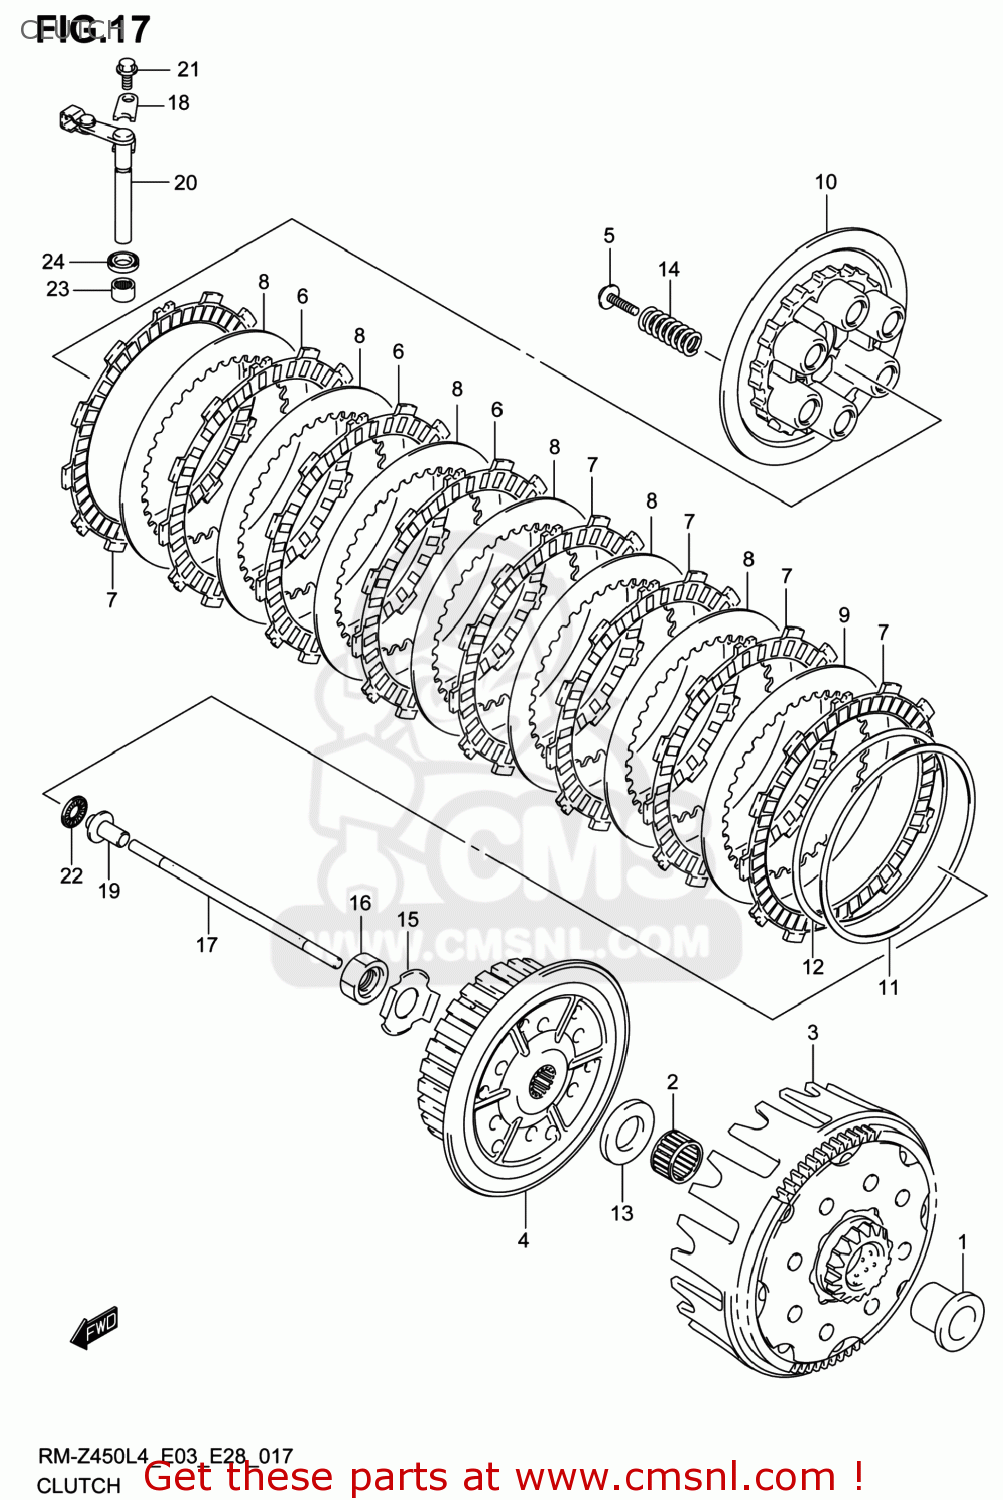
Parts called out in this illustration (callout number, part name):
1	SPACER,PRIMARY DRIVEN GEAR
2	BEARING(28X32X26)
3	GEAR ASSY,PRI DRIVEN
4	HUB,CLUTCH SLEEVE
5	BOLT,CLUTCH SPRING(6X25)
6	PLATE,CLUTCH DRIVEN NO.1 (NAS)
7	PLATE,CLUTCH DRIVE NO.2 (NAS)
8	PLATE,CLUTCH DRIVEN (NAS)
9	PLATE,CLUTCH DRIVEN (NAS)
10	DISC,CLUTCH PRESSURE
11	SEAT,WAVE WASHER
12	WASHER,CLUTCH PLATE WAVE
13	WASHER(22.5X39X3)
14	SPRING
15	WASHER,CLUTCH SLEEVE HUB LOCK
16	NUT
17	ROD,CLUTCH PUSH
18	RETAINER,CL RELEASE CAMSHAFT
19	PIECE,CLUTCH PUSH
20	CAMSHAFT,CLUTCH RELEASE
21	BOLT(6X12)
22	BEARING(10X22X2.8)
23	BEARING(10X14X10)
24	SEAL,OIL(10X17X5)
